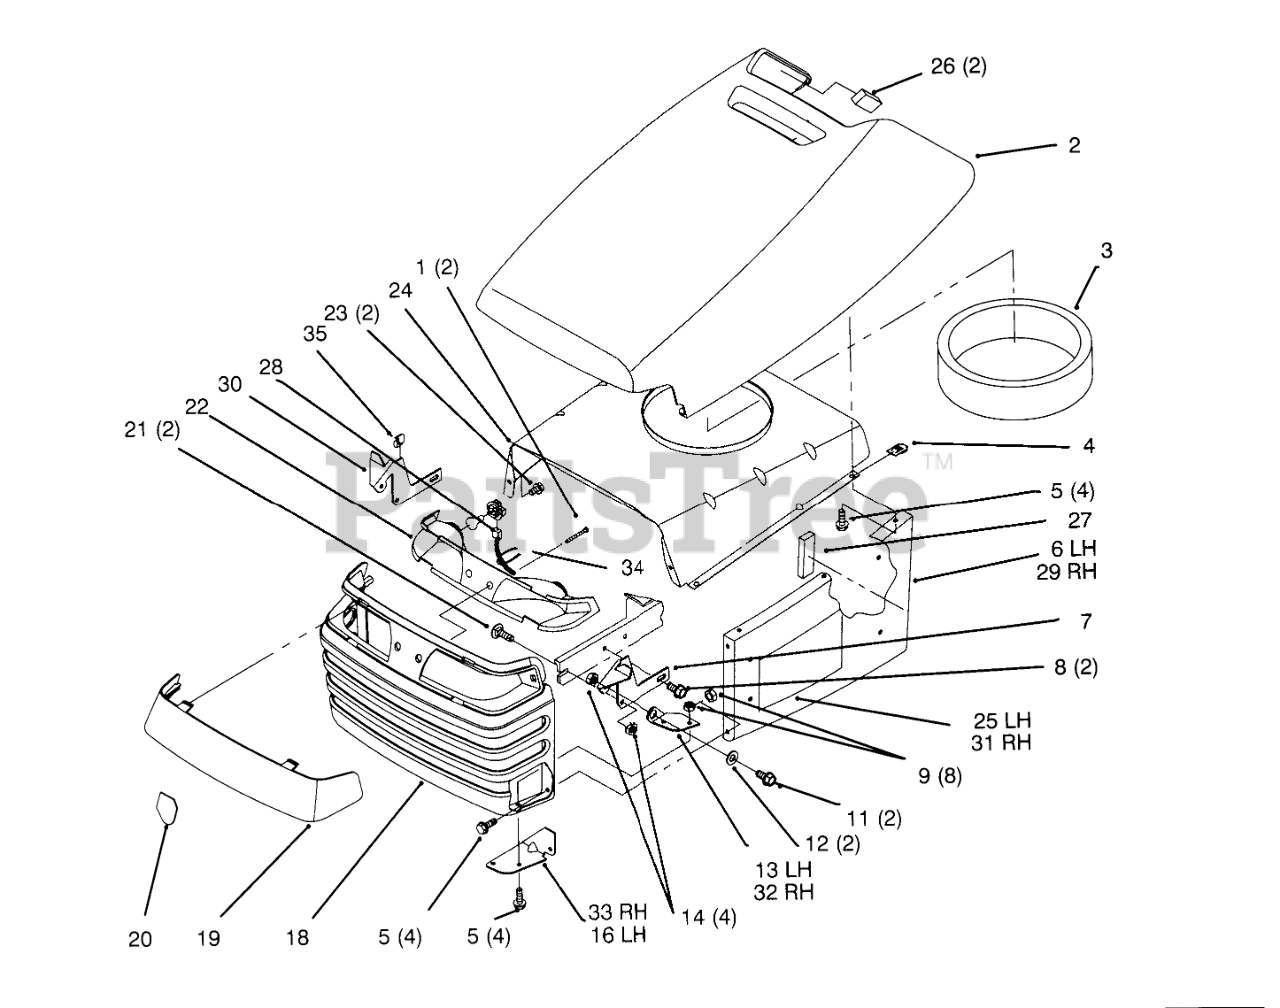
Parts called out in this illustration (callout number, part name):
2	HOOD ASM
3	Inlet-Seal Air (Only On: 72103)
3	Inlet-Seal Air (Only On: 72042, 72043, 72062, 72063)
5	SCREW-HWH
6	HOOD-SIDE, LH
7	BRACKET-HINGE, LH
8	SCREW-HWHTF
9	NUT-LOCK, HHF
11	SCREW-HH
12	BUSHING
13	HINGE-HOOD, LH
14	NUT-LOCK, NI
16	BRACKET-HOOD HINGE, RH
18	Screen/Grill ASM
19	LENS - HEADLIGHT
20	EMBLEM-HORSEHEAD
21	BOLT-CARR
22	HEADLIGHT REFLECTOR ASM
23	SCREW-PLASTITE
24	BAFFLE-HOOD, UPPER
25	DECAL - LH HOOD
26	Foam-Hood
27	FOAM-SIDEPANEL
28	HARNESS-WIRE, LIGHTS
29	HOOD-SIDE, RH
30	BRACKET-HINGE, RH
31	DECAL - RH HOOD
32	HINGE-HOOD, RH
33	BRACKET-HOOD HINGE, LH
34	TIE-CABLE
35	CLIP-RETAINER, WIRE
